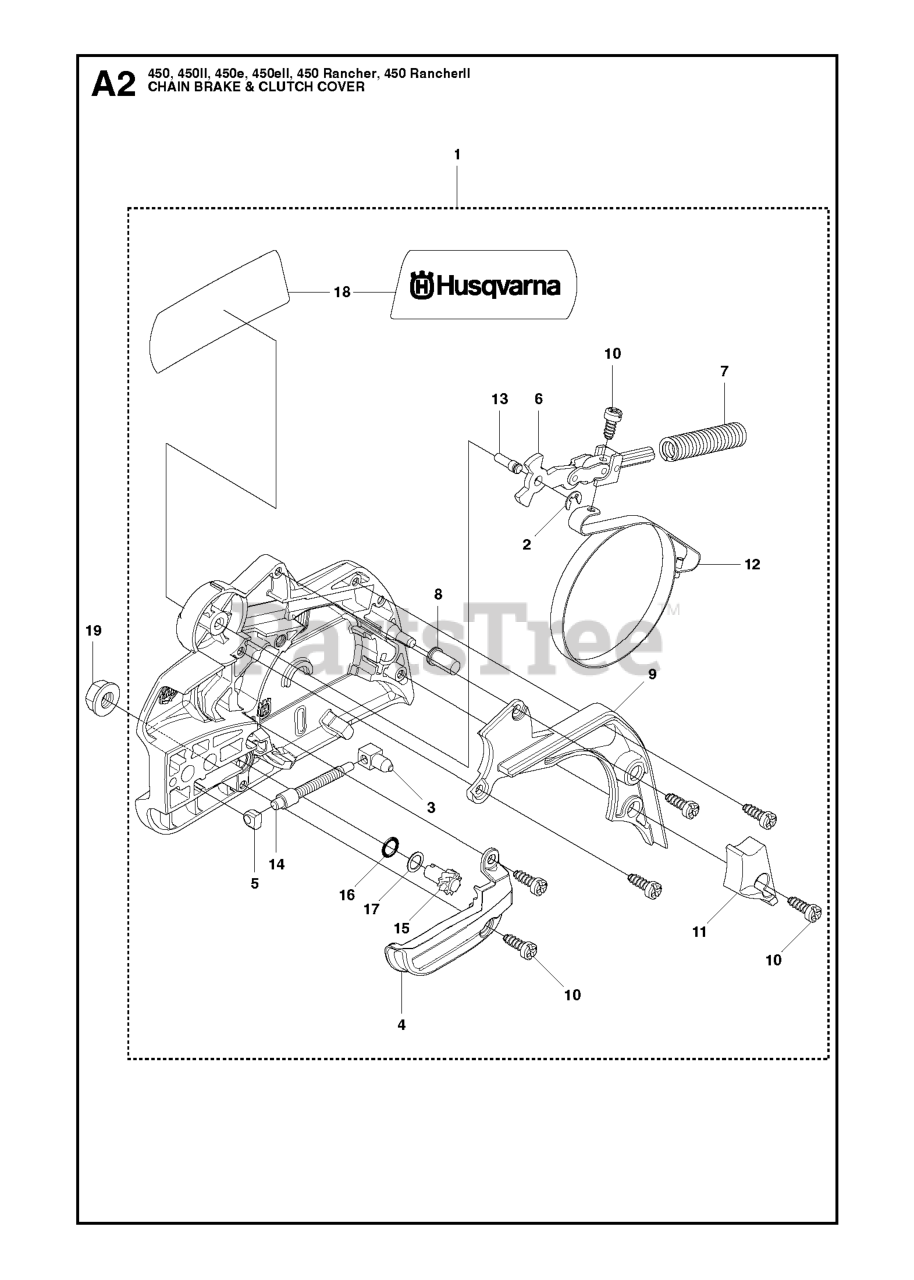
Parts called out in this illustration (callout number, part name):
1	CLUTCH COVER
4	CHAIN GUIDE
9	COVER, CHAIN BRAKE
11	WEAR GUARD, CHAIN
12	BRAKE BAND
15	WORM WHEEL
18	LABEL 400 SERIES
19	NUT M8 FLANGE
